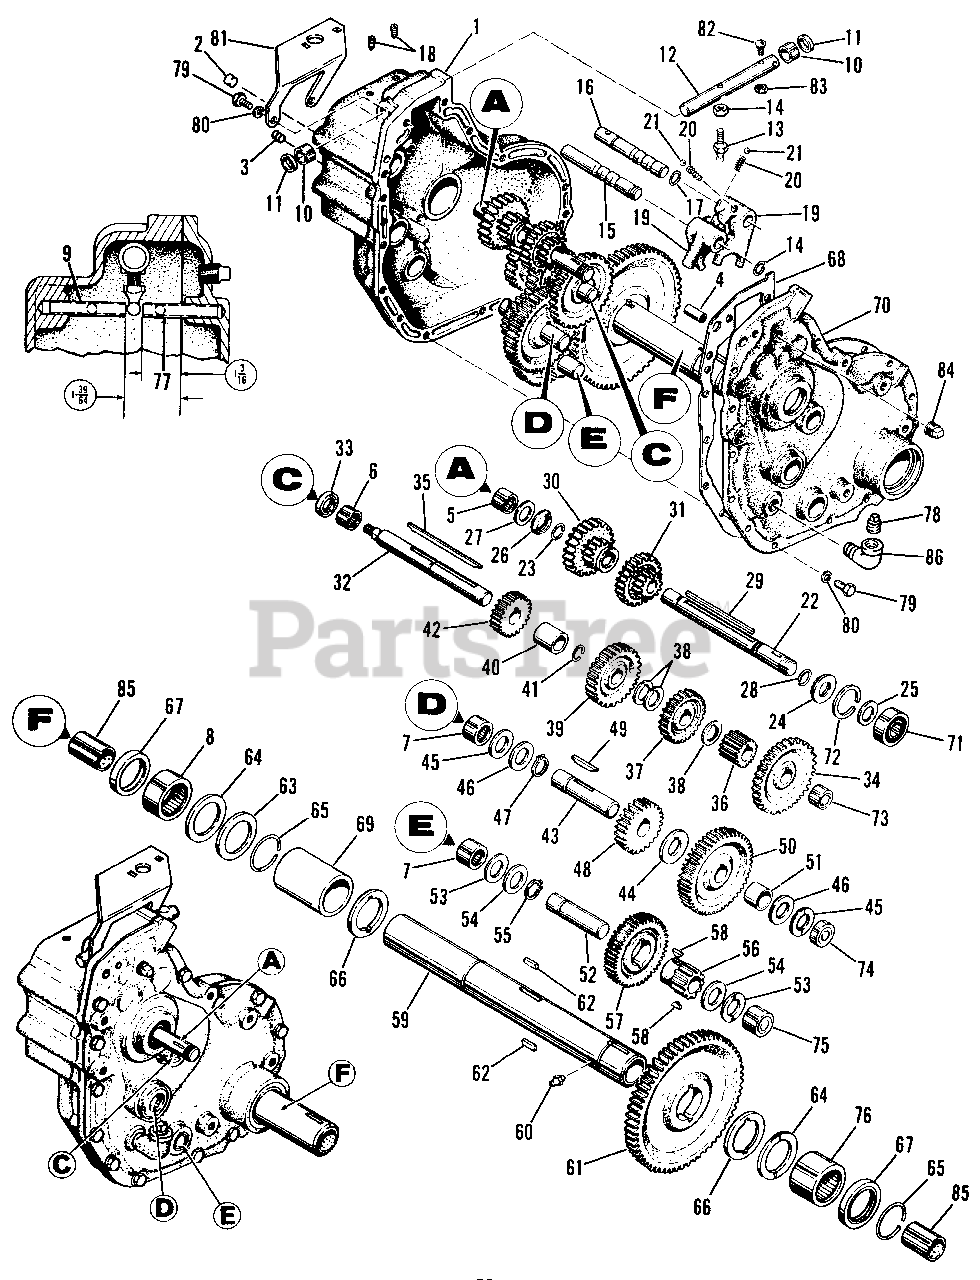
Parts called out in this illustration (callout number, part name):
1	Case, Gear Assy. Complete w/bearings & dowel pins (Includes 2 thru 7)
2	Expansion Plug
3	Set Screw, Cup Pt. Socket Hd., 3/8"-16 x 3/8"
4	Roll Pin, 3/8" x 1"
5	Needle Bearing
6	Needle Bearing
7	Needle Bearing
8	Needle Bearing
12	Shift Rod
13	Shift Stem
14	Full Lock Hex, Nut, 3/8"-24 N.F.
15	Shifter Shaft Rev., Med.
16	Shifter Shaft High, Low
17	Retaining Ring
18	Set Screw, Hollow Head, Cone Pt., 5/16"-18 x 1/2"
21	Shift Lock Ball
22	Pulley Shaft
23	Retaining Ring
28	Retaining Ring
30	Gear Assy., II & IV
31	Pinion Assy., I & III
32	Shaft, 1st Intermediate
34	Driven I, Gear
36	Pinion, 1st Intermediate
37	Pinion, Driven, III
38	Trans. Gear Spacer
39	Driven II Gear
41	Retaining Ring
42	Pinion, Reverse, IV
43	Shaft, 2nd Intermediate
47	Retaining Ring
48	Pinion, 2nd Intermediate
50	Gear, 2nd Intermediate
52	Shaft, 3rd Intermediate
55	Retaining Ring
56	Pinion, 3rd Intermediate
57	Gear, 3rd Intermediate
58	Key Woodruff
59	Axle Tube w/bushing
60	Grease Fitting
61	Drive Gear
66	Axle Tube Washer
68	Gear Case Gasket
69	Axle Tube Spacer
70	Gear Case Cover, Complete w/bearings
71	Ball Bearing
72	Retaining Ring
73	Needle Bearing
74	Needle Bearing
75	Needle Bearing
76	Needle Bearing
77	Roll Pin Assembly
78	Pipe Plug, 3/8"
79	Hex Capscrew, 5/16"-18 x 1"
80	Lockwasher, 5/16"
81	Switch Support
82	Carriage Bolt, 5/16"-18 x 1"
83	Jane Nut, 5/16"-18
84	Pipe Plug, 3/8"
86	Elbow, 3/8" x 90
